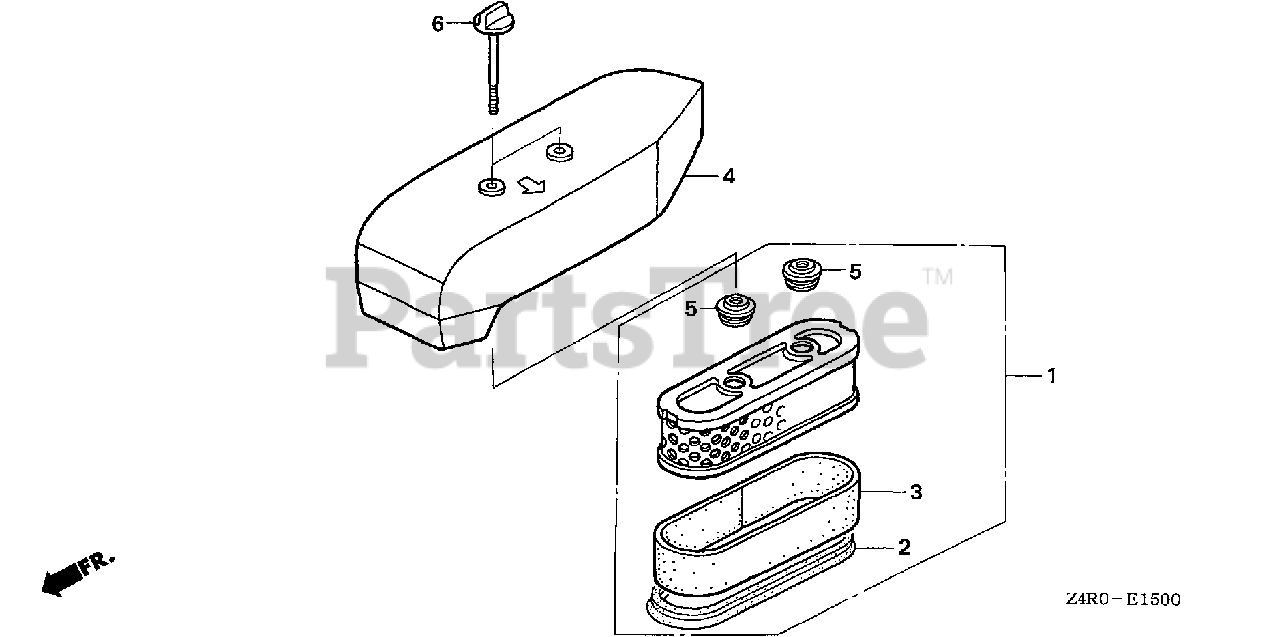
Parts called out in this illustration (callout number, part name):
1	ELEMENT, AIR CLEANER (TOYO)
2	GASKET, ELEMENT
3	FILTER (OUTER)
4	COVER, AIR CLEANER *NH1* (BLACK)
5	GROMMET, AIR CLEANER
6	BOLT, AIR CLEANER (6X73)
